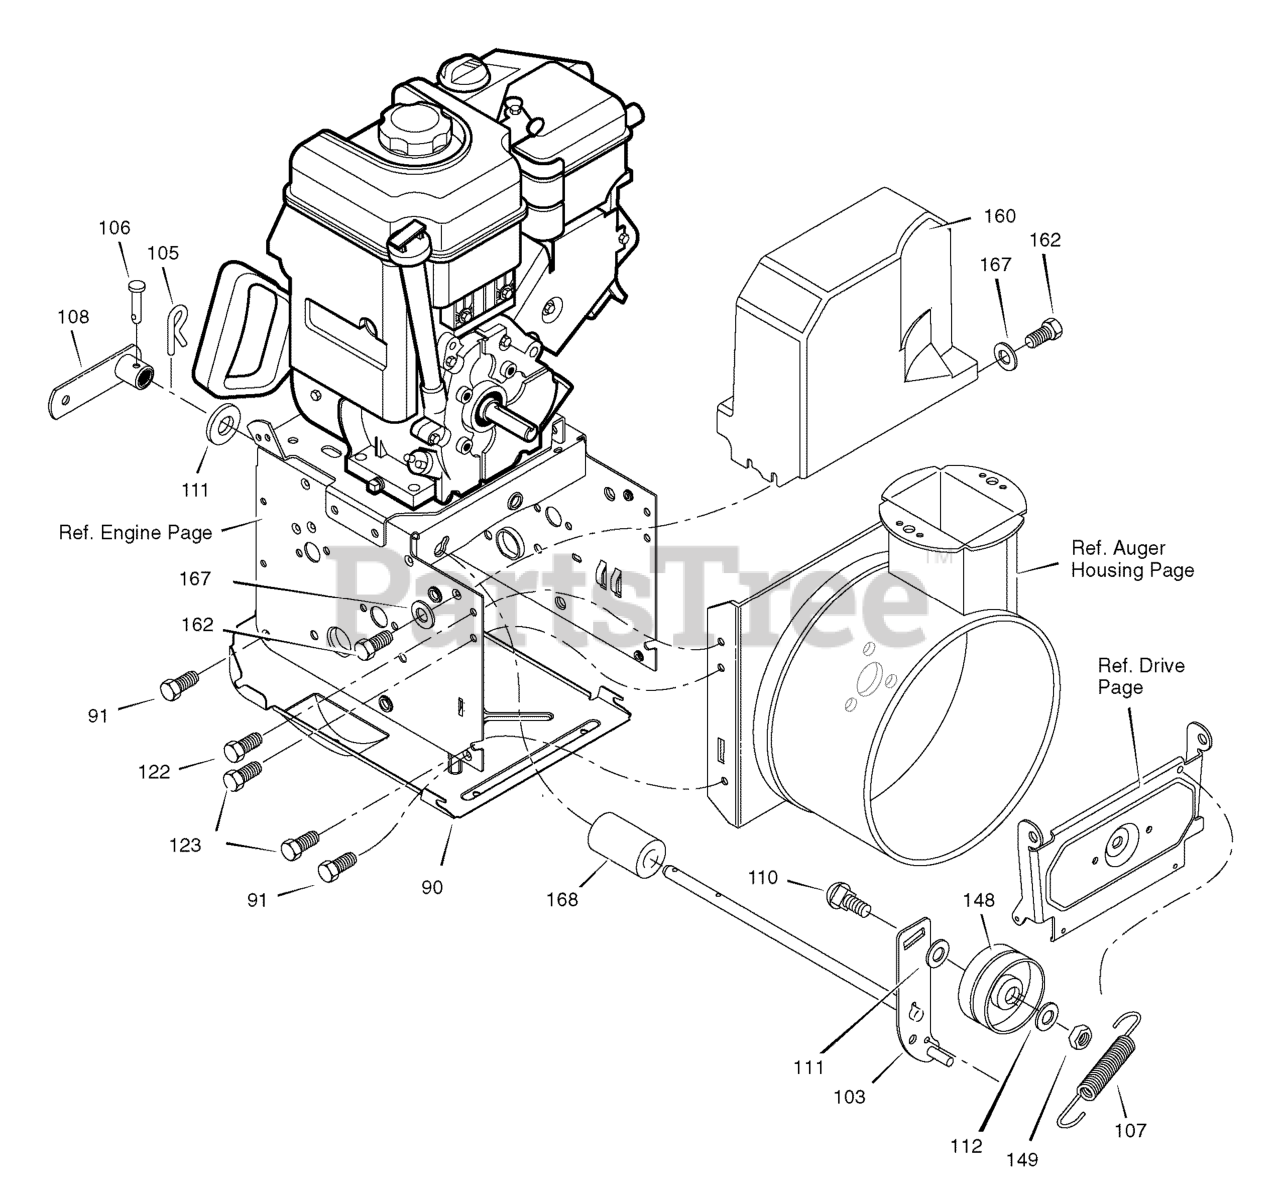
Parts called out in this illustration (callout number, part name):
90	COVER, BOTTOM
91	SCREW, 1/4-20 X .63
103	IDLER ASSEMBLY, AUGER
105	PIN, HAIR .38 DIA X 1.64LG
106	PIN, CLEVIS 3/16" DIA
107	SPRING, TENSION
108	ASSEMBLY SPRING ATTACH
110	BOLT, 3/8-16 X 1.25 CARRIAGE
111	WASHER, FLAT
122	SCREW, TAP 5/16-18 X .50
123	SCREW, TAP 5/16-18 X .75
148	PULLEY, IDLER
149	NUT, JAM 3/8-16
160	COVER, BELT
162	SCREW, TAP
167	WASHER, FLAT
168	SPACER, AUGER BRACKET
